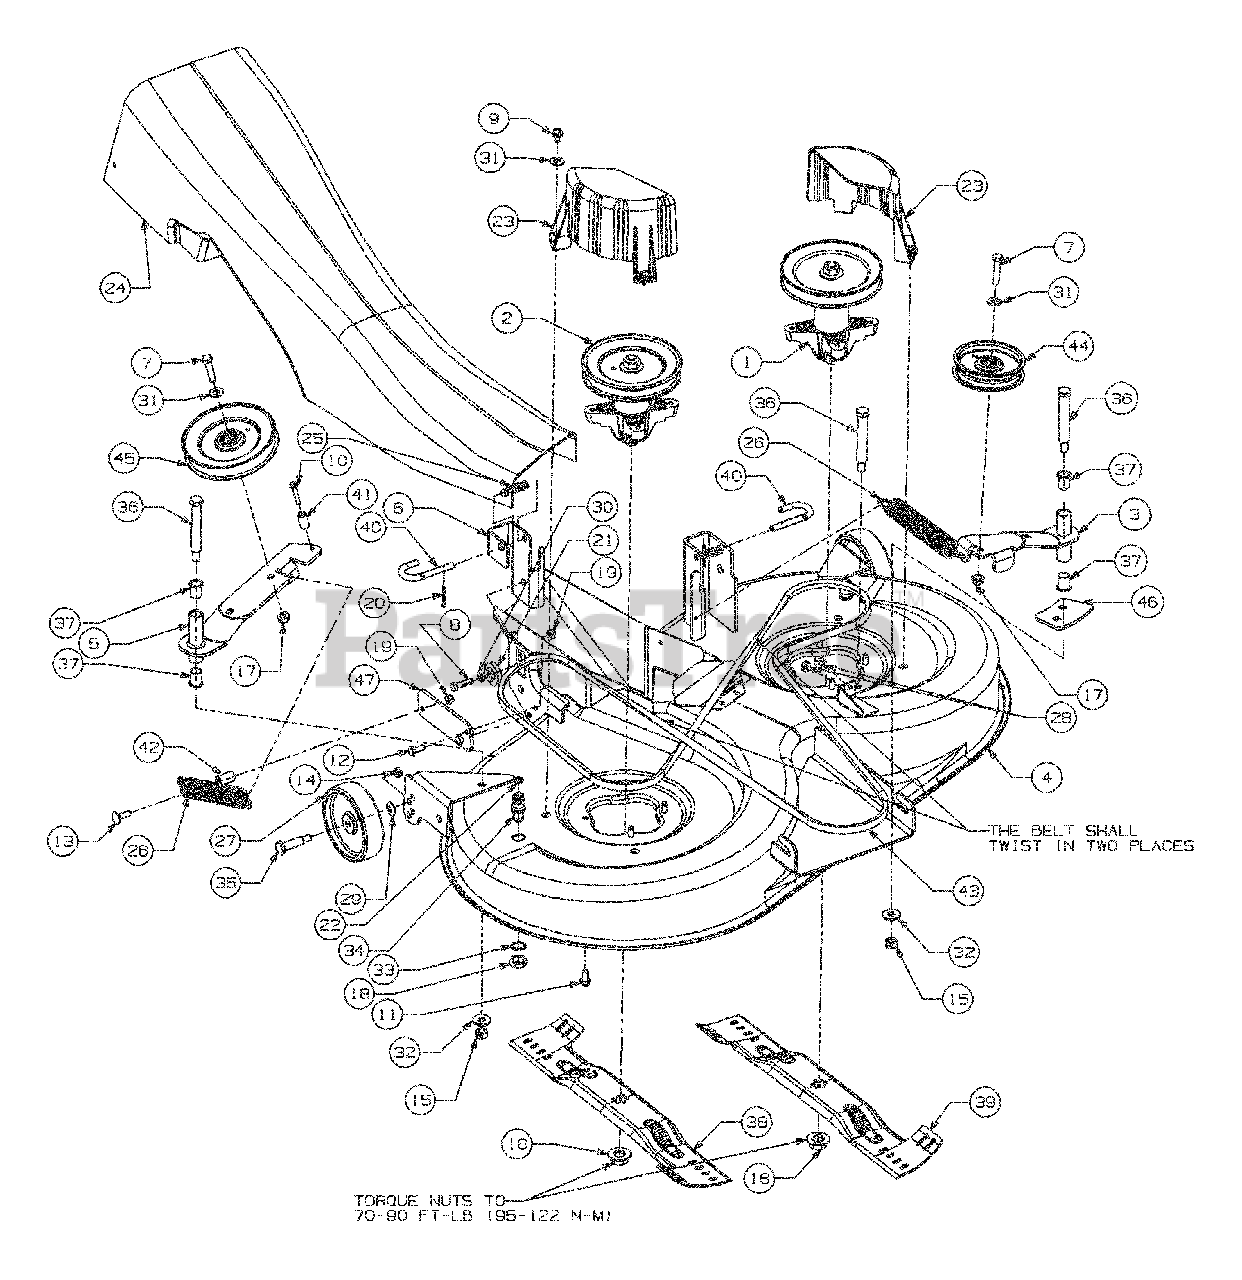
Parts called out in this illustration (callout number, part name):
1	SPDL ASM:PUL:6.418 DIA X .5625
7	HHCS:3/8-16:1.75:GR5:STD
8	HHCS:5/16-18:1.25:GR5:STD
9	SCR:TT:5/16-18:0.500:HXINDWSH
10	SCR:TT:1/4-20:1.500:HXINDWSH
11	SCR:LD:5/16-18:0.750:HXINDWSH
12	HHCS:M8-1.25:20.00:GR8.8:STD
13	BOLT:CRG:M8 X 1.25 X 50 LG
14	NUT:JAM:3/8-16:TOP LOCK
15	NUT:HEXLK:7/16-14:GRA:CTRLK
16	NUT:HEX FLG:5/8-18
17	NUT:FLGLK:3/8-16:GRF:TOP LK
18	NUT:HEX:M16-1.5 DIN 936
19	NUT:HEXLK:M8-1.25:NYLON DIN985
20	PIN:COT:1/8 X 1.25
21	ADJ:DECK:GEAR
22	SEAL:O-RG:16mm OD X 11mm ID
23	CVR:DECK:BELT:92cm/105cm
24	CHUTE:DIS:RR:105CM DECK
25	SPR:CMPRS:.406X.531X1.75 LG
26	SPR:EXT:1.25 DIA X 8.224 LG
27	DECK WHEEL 5.0 X 1.38
28	BMPR: .62 DIA X .3
29	WASH:BELL:.375 X .870 X .063
30	WASH:LOCK:5/16:REGULAR DUTY
31	WASH:FLAT:.406 X .875 X .059
32	WASH:FLAT:.469 X 1.125 X .125
33	WASH:LOCK:SCHNORR 17X23.8X1.95
34	NOZ:DECK:WATER
35	SHLD-SCR .498 DIA X 1.53 LNG
36	SCR:SHLDR:.625 X 3.50:7/16-14
37	BRG:FLG:.630 ID X .693 OD X .875
38	BLADE:RH:21.35 LG:STAR BAG
39	BLADE:LH:21.35 LG:STAR BAG
40	ROD:HNDL:DECK REL .375 DIA
41	SPCR:14MM OD X 7MM ID
42	SPCR:16X8X27 DIN 2391
43	BELT:V TYP:5 L X 106 LG KEVL
44	PUL:IDLR:4.0 DIA.
